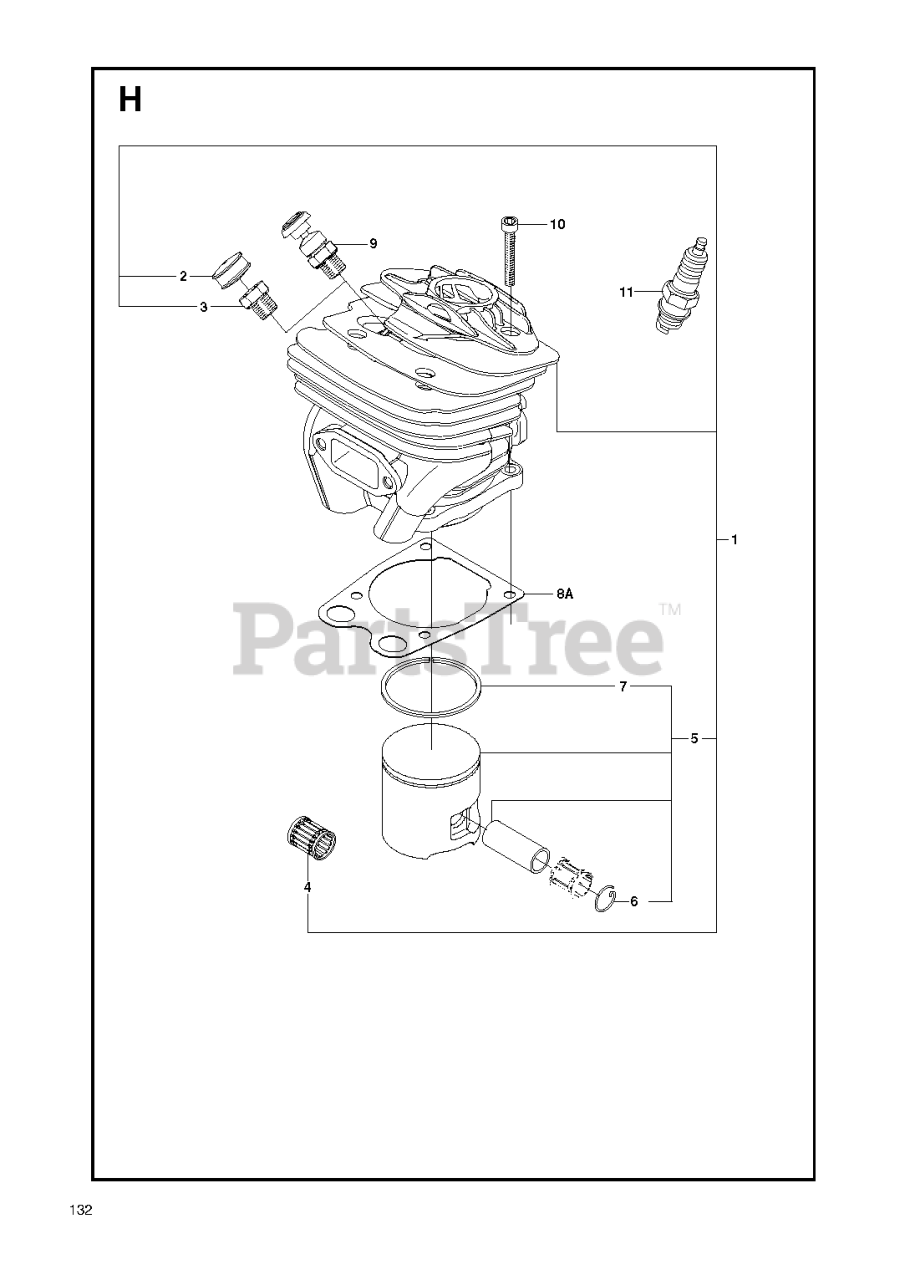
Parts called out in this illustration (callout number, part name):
1	%CYLINDER
3	CYLINDER PLUG
4	SUPPORT BUSHING
5	PISTON 49 MM
6	WRIST PIN CLIP
7	PISTON RING
8	GASKET SET
9	VALVE
10	SCREW MC6S 5X25
11	BPMR7A NGK SPARK PLUG
